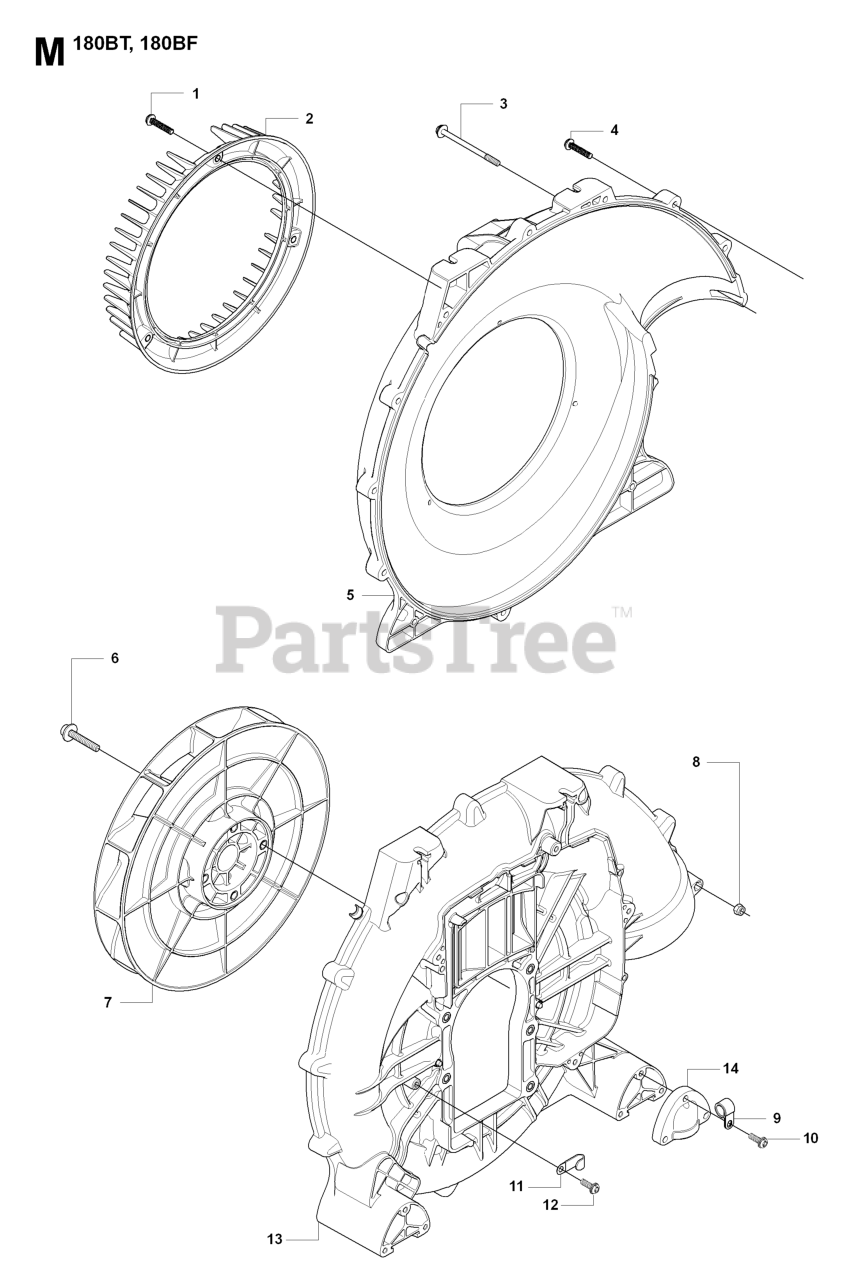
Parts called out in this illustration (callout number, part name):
1	SCREW
2	COVER (FUNNEL)
4	SCREW
5	VOLUTE COVER
6	RP_BOLT
8	NUT
10	SCREW
11	RP_CLAMP
12	SCREW
13	VOLUTE CASE
